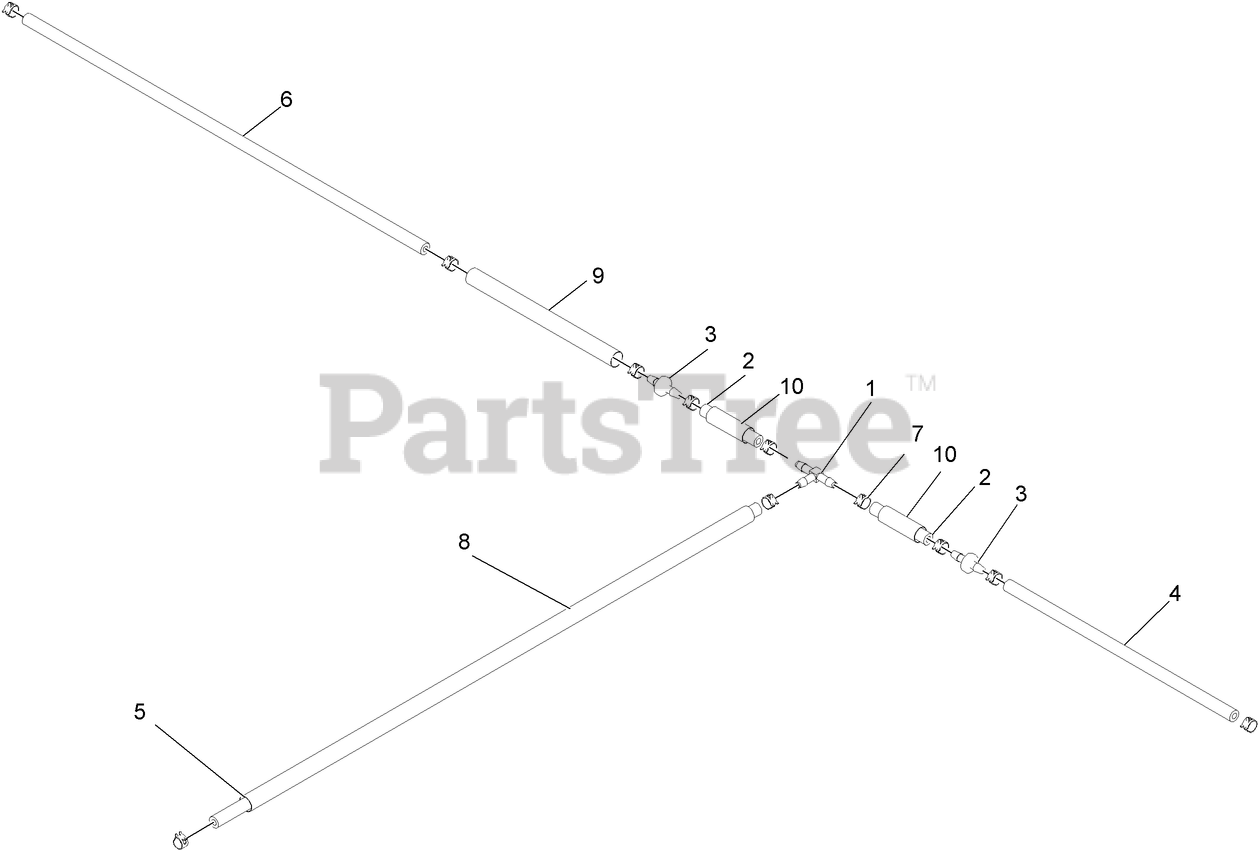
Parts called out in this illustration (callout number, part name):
1	FITTING-TEE, BARBED
2	HOSE-FUEL
3	VALVE-CHECK, FUEL
4	HOSE-FUEL
5	HOSE-FUEL
6	HOSE-FUEL
7	CLAMP-HOSE
8	Valve-Check, Fuel
9	SLEEVE-THERMAL
10	Hose-Fuel Line 30"
